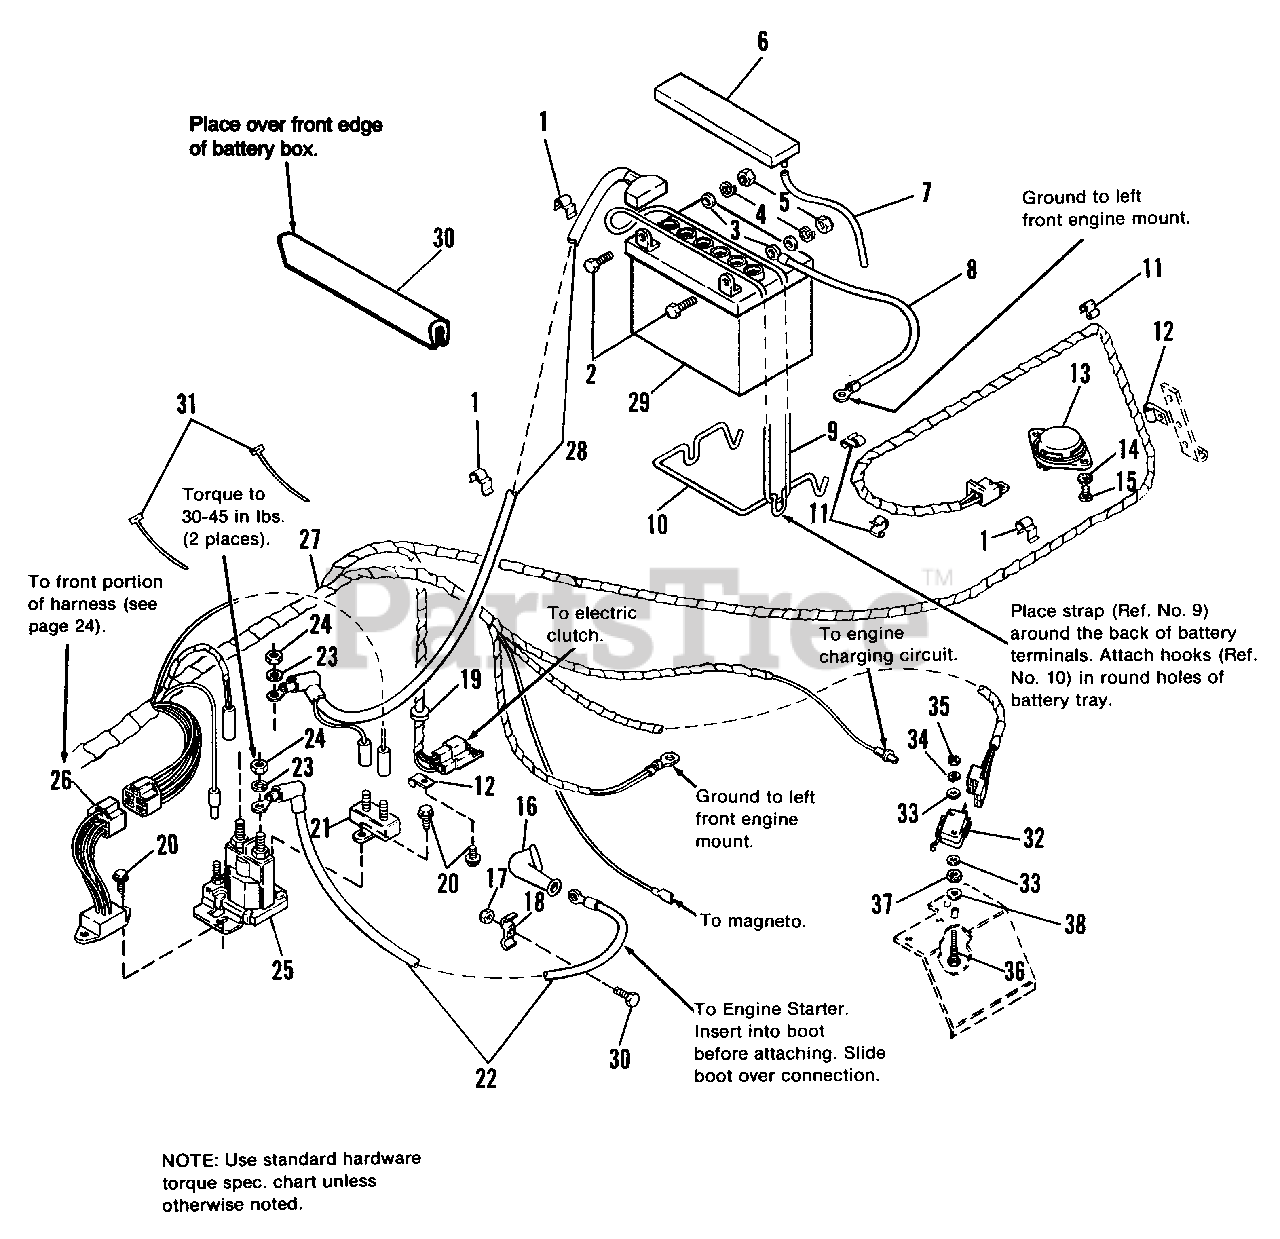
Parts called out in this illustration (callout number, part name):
2	CAPSCREW, Hex, 1/4-20 x 3/4
3	WASHER, 1/4
4	LOCKWASHER, 1/4
5	NUT, Hex, 1/4-20
6	VENT CAP, Battery
7	HOSE, Drain, Battery
8	CABLE ASSY. (Battery to Ground)
9	STRAP, Battery
10	BRACE, Battery Hold Down
11	CUP, Wire
12	CLAMP, Wire
13	SWITCH, Seat
14	LOCKWASHER, Ext. 1/4
15	SCREW, Rd. Hd., 1/4-20 x 3/4
16	COVER, Terminal
17	NUT, Hex, Whizlock, 1/4-20
20	SCREW, Taptite, 1/4-20 x 3/4
21	CIRCUIT BREAKER
22	CABLE ASSY., Starter
23	LOCKWASHER, 5/16
24	NUT, Hex, 5/16-24
26	MODULE, DSI, Interlock
27	WIRING HARNESS
28	CABLE ASSY. (Battery Positive)
29	BATTERY, 12 Volt
32	SWITCH, Tandem
33	WASHER, #6
34	LOCKWASHER, #5
35	NUT, Hex, #5-40
36	STUD, Switch, Mounting
37	NUT, Hex, Lock 1/4-20
38	WASHER, 1/4
